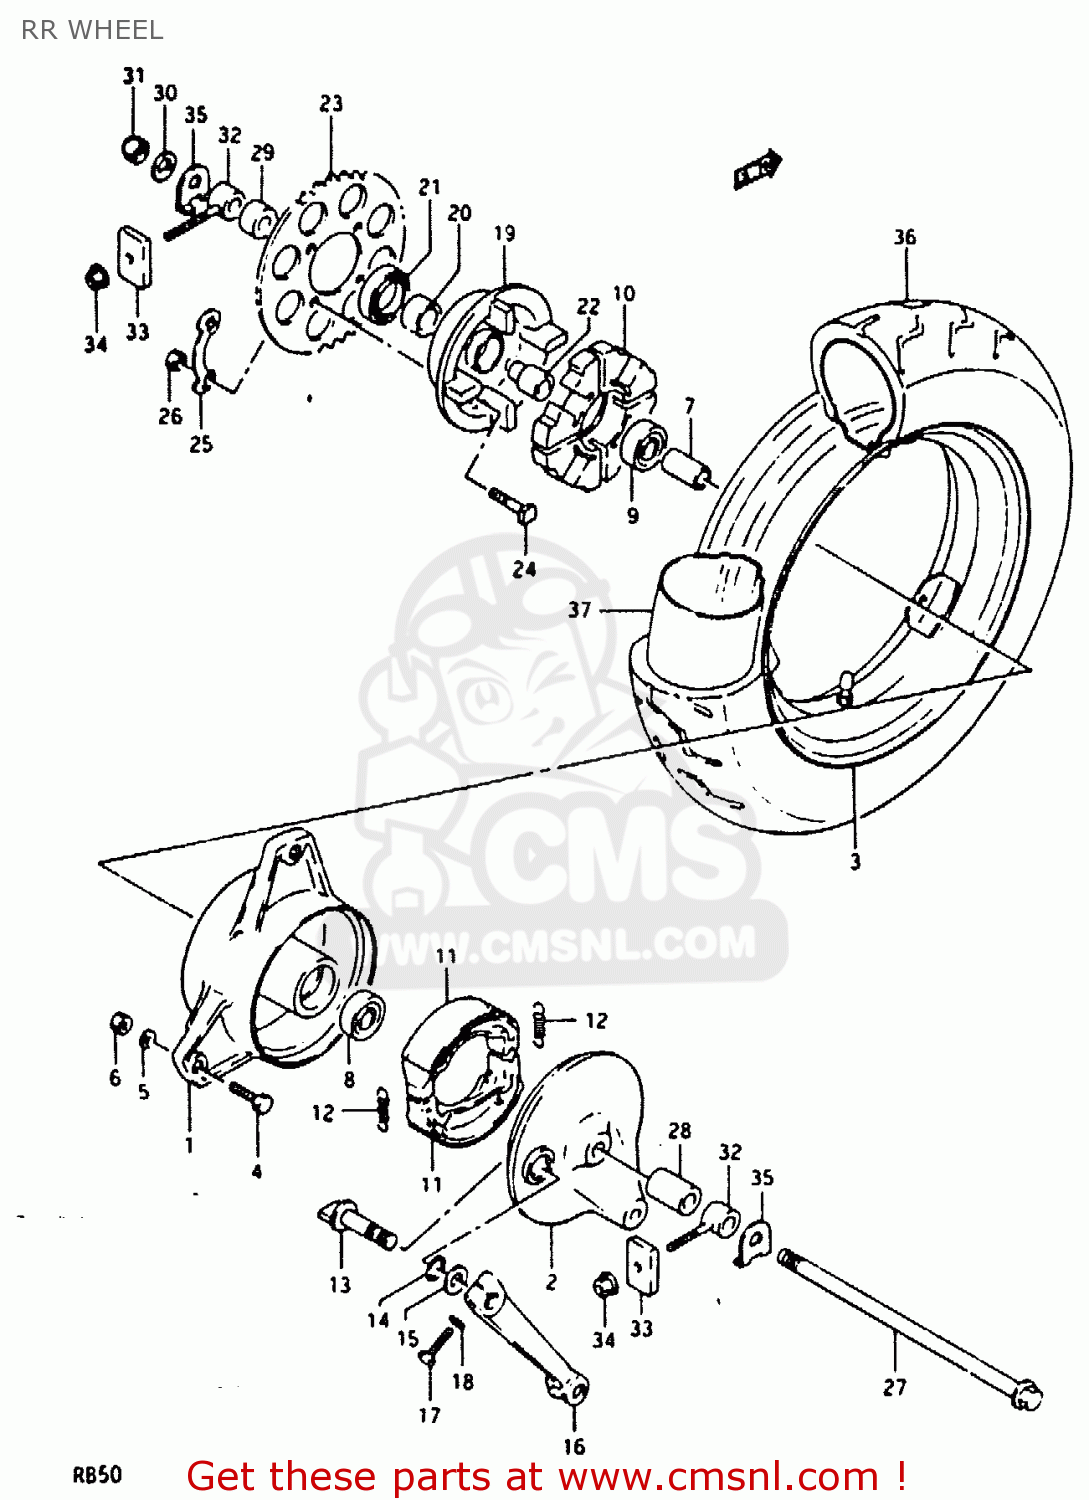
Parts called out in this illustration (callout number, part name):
1	HUB,REAR WHEEL
2	PANEL,REAR HUB
3	WHEEL,RIM
4	BOLT(8X21.5)
5	LOCK WASHER
6	NUT
7	SPACER (12.6X19X61.5)
8	BEARING
9	BEARING
10	CUSHION,REAR DRUM
11	SHOE,BRAKE
12	SPRING(L:34)
13	CAM,FRONT BRAKE
14	O-RING (D:2.4 ID:13.8)
15	WASHER (14.5X22X1.6)
16	LEVER,RR BRAKE CAM
17	BOLT
18	WASHER,LOCK
19	DRUM,REAR SPROCKET MOUNT
20	BEARING(17X40X12)
21	SEAL OIL(25X40X6)
22	RETAINER,RR SPROCKET DRUM
23	SPROCKET,REAR
24	BOLT(8X33.5)
25	WASHER
26	NUT
27	AXLE,RR
28	SPACER (12.2X22X29)
29	SPACER
30	WASHER
31	NUT 12MM
32	ADJUSTER COMP,CHAIN
33	PLATE,CHAIN ADJUSTER GUIDE
34	NUT
35	WASHER,CHAIN ADJUSTER
36	TIRE,REAR 3.50-10-2PR
37	TUBE,INNER
